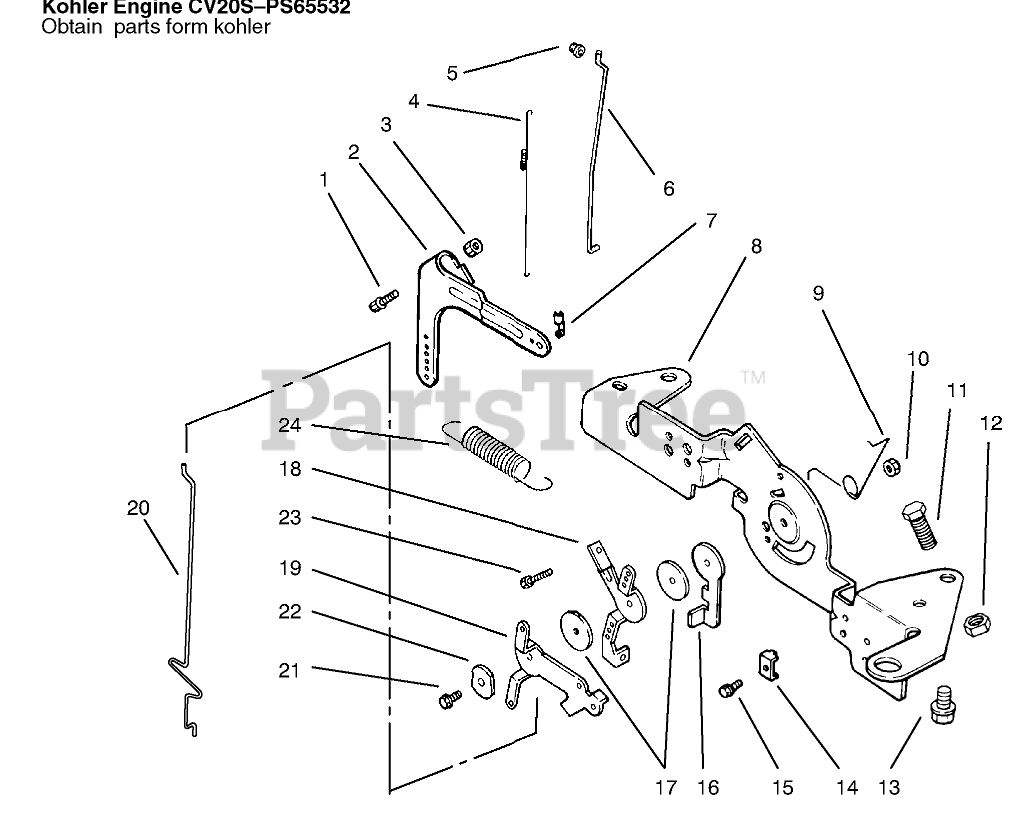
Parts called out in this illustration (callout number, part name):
1	Screw
2	Lever-Governor
4	Spring-Linkage
5	Bushing-Linkage
6	Linkage-Throttle
7	Bushing-Linkage
8	Bracket-Control
9	Spring-Choke Return
10	Nut M5x0.8
11	Screw
12	Nut
13	Screw
14	Clamp
15	Screw
16	Lever-Actuator, Throttle
17	Washer
18	Lever-Throttle Control
19	Lever-Choke
20	Linkage-Choke
22	Washer-Wave
24	Spring-Governor
